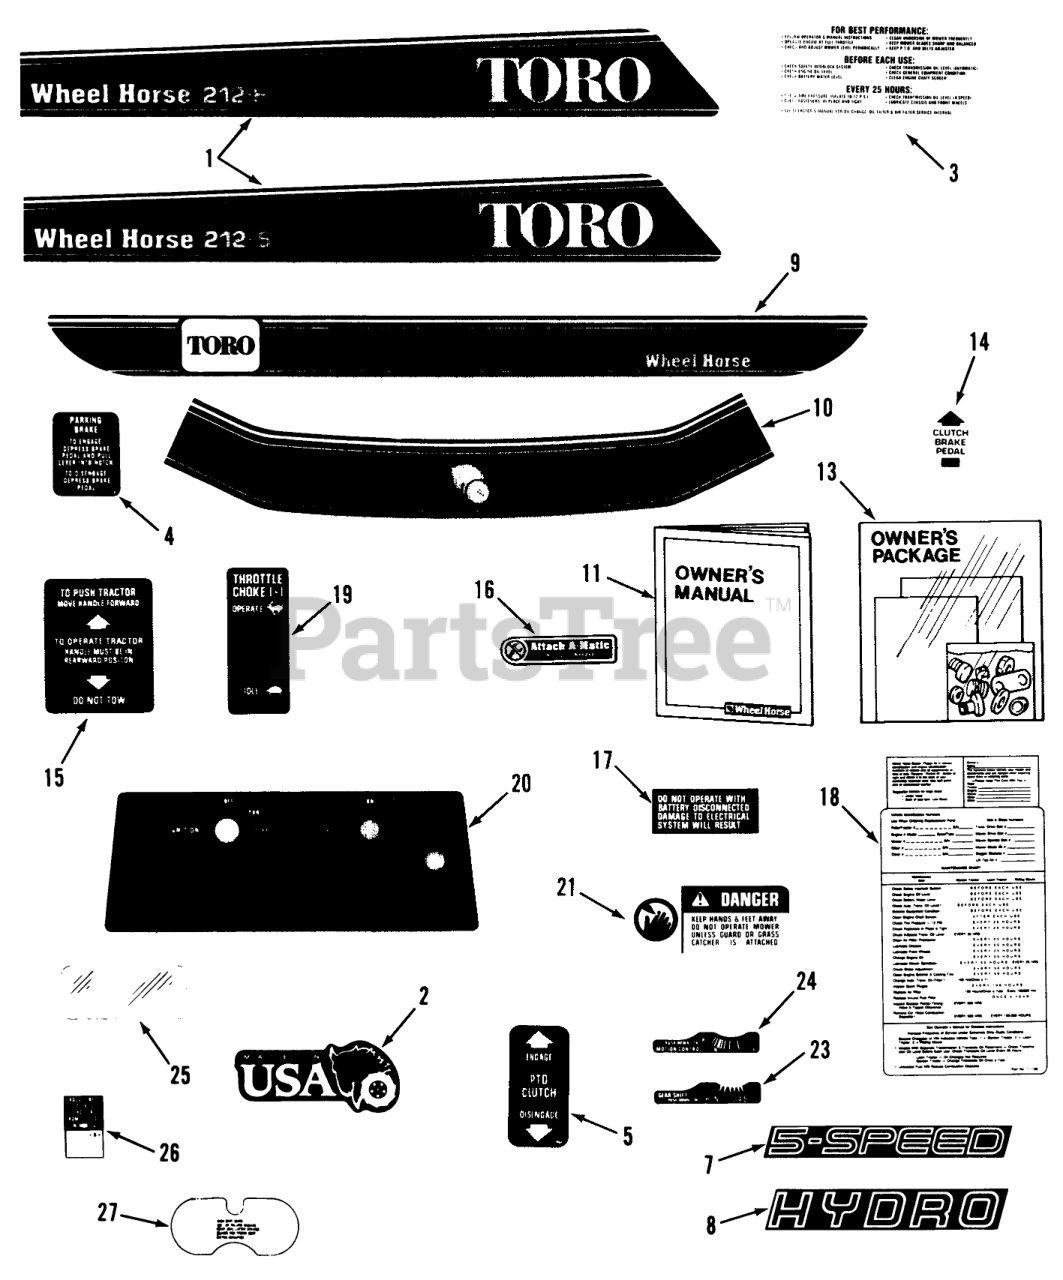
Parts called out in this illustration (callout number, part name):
1	DECAL-HOOD 212-5 R H
2	Decal-Made In USA
3	Decal-Hood Rear
4	DECAL PARKING BRAKE
5	DECAL-PTO
7	DECAL-MODEL 5-SPEED
8	DECAL-MODEL HYDRO
9	DECAL-FENDER
10	DECAL-FRONT HOOD
13	Loose Parts Package (212-5)
13	Loose Parts Package (212-H)
14	DECAL CLUTCH & BRAKE
15	DECAL-PUSH
16	Decal-Attach-A-Matic
17	DECAL ELECT SYSTEM
18	MAINTENANCE-DECAL
19	DECAL-THROTTLE
20	DECAL-BACK PLATE
21	DECAL-DANGER
23	DECAL-SHIFT 5-SPEED
24	DECAL-MOTION CONTROL
25	DECAL-OVERLAY
26	DECAL-PTO BELT ADJ
27	DECAL-SEAT LIFTER
